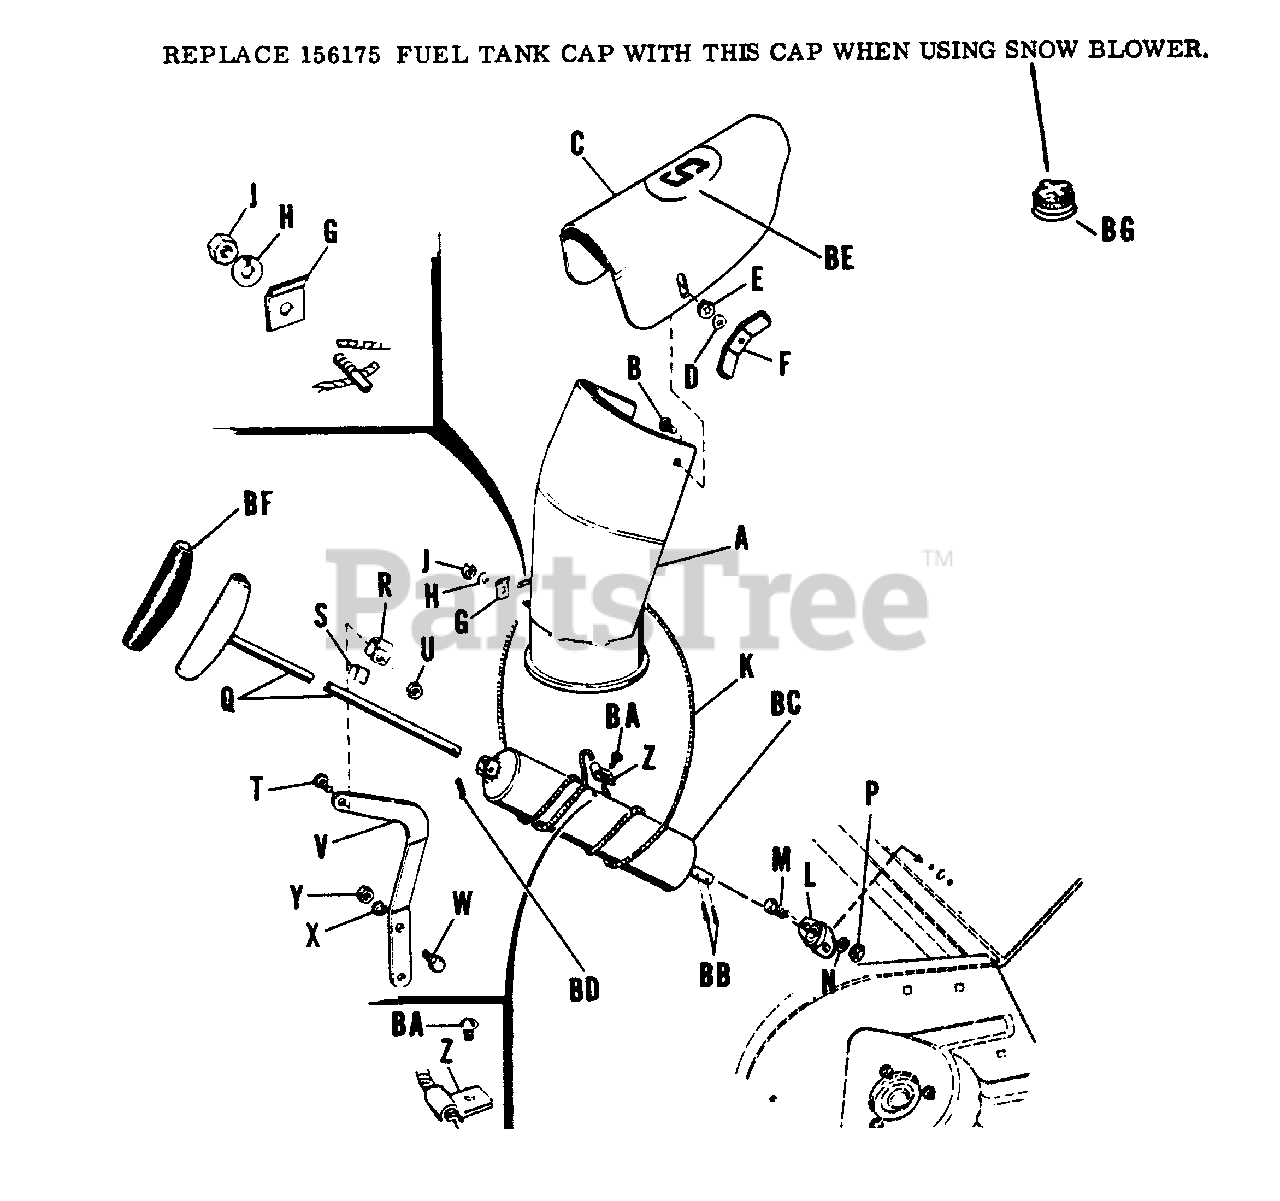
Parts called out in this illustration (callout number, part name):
A	Spout Assembly
B	Carriage Bolt, 5/16"-18 x 3/4"
C	Spout Extension
D	Plain Washer, 3/8"
E	Special Hex. Lock Washer, 3/8"
F	NUT, Wing, 5/16-18
H	Lock Washer 5/16"
J	Full Hex. Nut 5/16"-18
K	Spout Cord
M	Hex Capscrew. 1/4"-20 x 5/8"
N	Lock Washer 1/4"
P	Full Hex. Nut 1/4"-20
S	Guide Liner
T	Hex. Capscrew, 5/16"-18 x 1-1/4"
U	Rod Guide Support
V	Full Hex. Lock Nut, 5/16"-18
W	Hex. Capscrew, 3/8"-16 x 1-1/4"
X	Lockwasher 3/8"
Y	Hex. Nut, 3/8"-16
BA	Self-Tapping Screw, 1/4"-20 x 1/2"
BB	Cotter Pin, 3/32" x 5/8"
BC	Control Tube, w/Socket
BD	Cotter Pin, 5/32" x 1"
BF	Handle Cover
BG	Can-Fuel Tank
